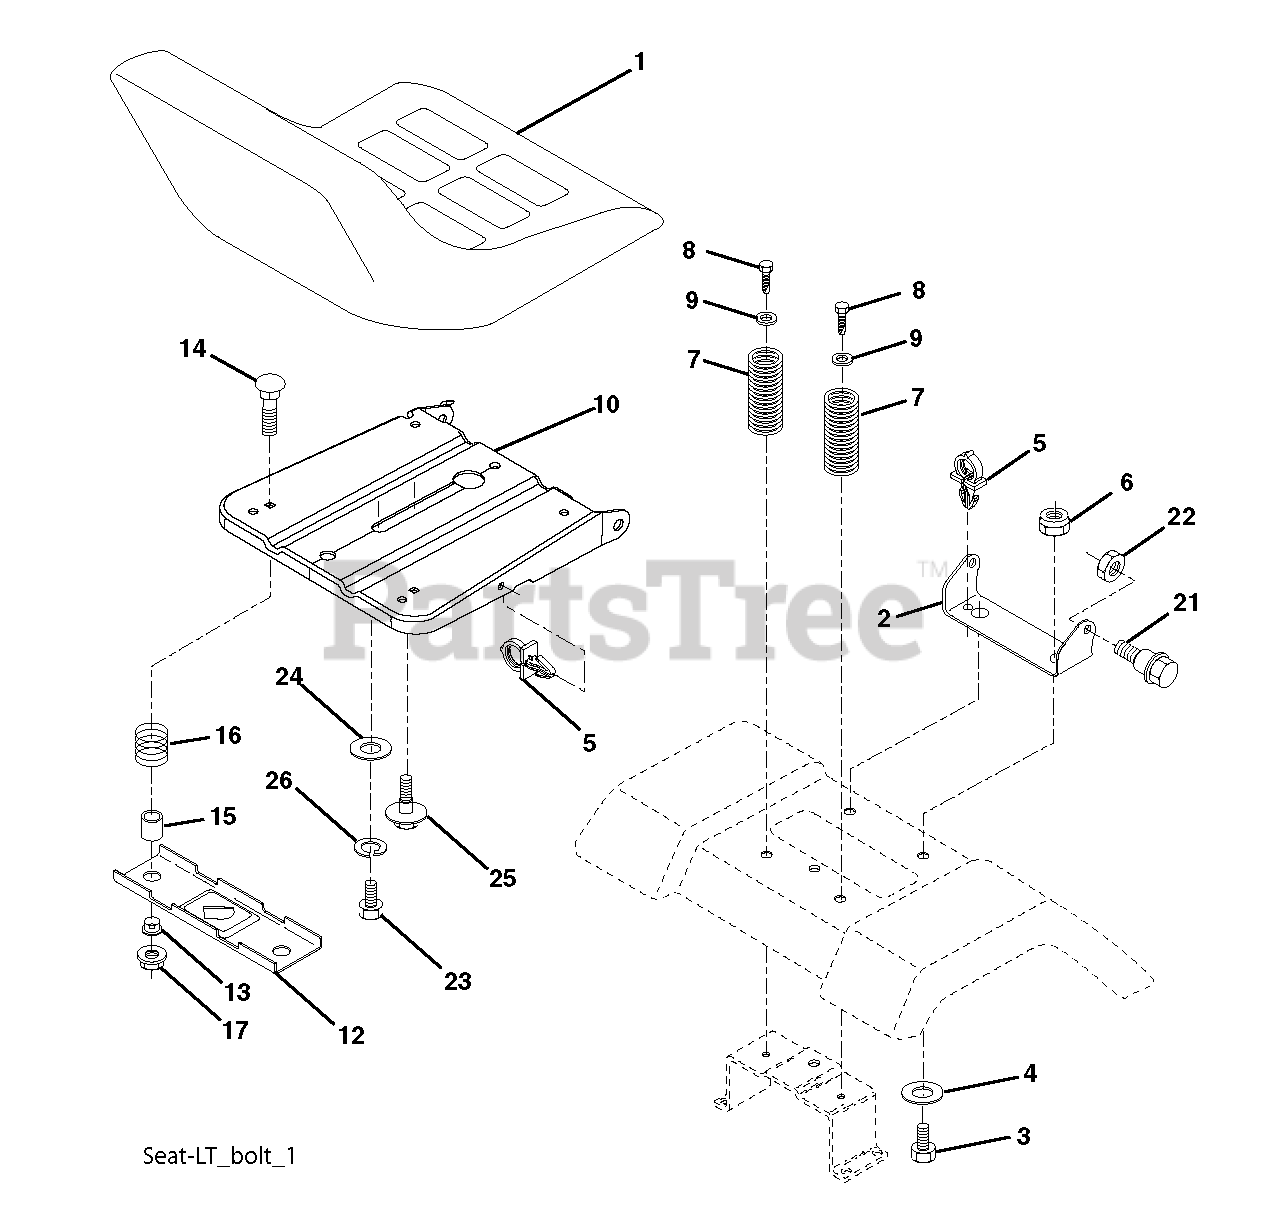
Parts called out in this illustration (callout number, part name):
1	SEAT.XG090.BLK.KB/BLT.NO-LOG
2	SEAT PIVOT BRKT
3	BOLT, HEX 3/8-16X1
6	NUT
7	SPRING COMPRESSION
8	SCREW 3/8-16X1
9	WASHER
10	PAN.ASM.SEAT.1SLOT
12	BRKT.MNTNG.SWITCH.SEAT
14	BOLT.ROUND.HEAD.SQUARE.NECK
15	SPACER SPLIT 28X.96
17	NUT T
21	BOLT.SHOULDER.5/16-18
22	NUT.71038.31-18.HEX.NYLOCK
23	BOLT.HEX.BLACK
